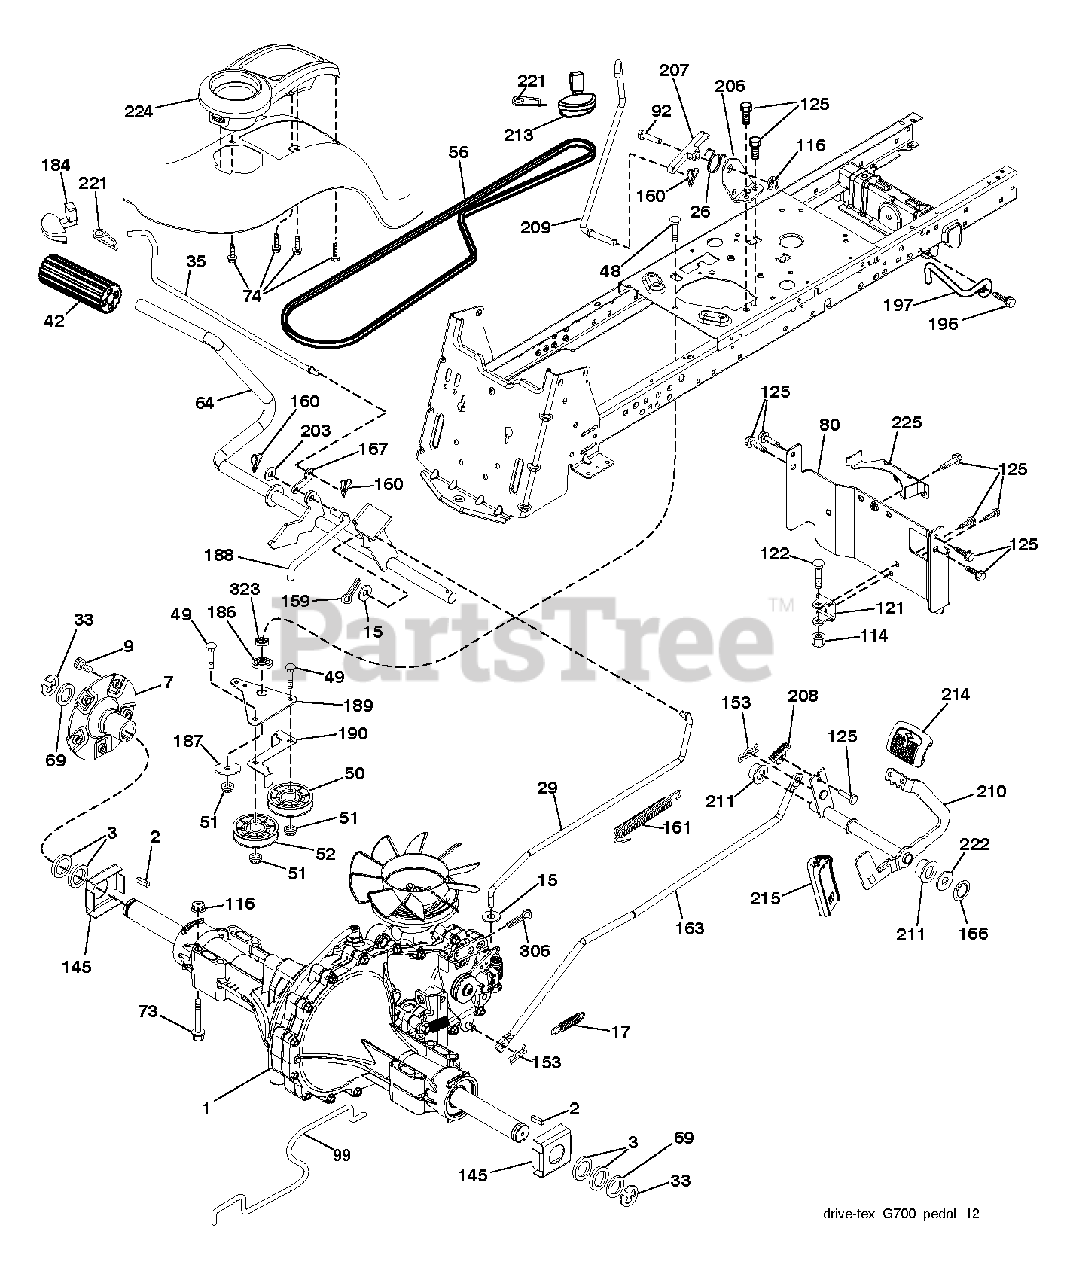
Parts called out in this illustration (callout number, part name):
2	KEY 1/4 X 2.5
3	WASHER T
7	HUB.ASM.WHEEL.REAR.23"TEX
9	HUB BOLT
15	WASHER
17	SPRING.BRAKE.HG3000/3500
26	SPRING.RETURN.CRUISE
29	ROD BRAKE
33	E RING HYT
35	ROD.BRAKE.PARKING.STEALTH
48	BOLT.3/8-16X1.50
50	IDLER.FLAT.910.OFFSET
51	NUT LOCK FLG 3/8-16 UNC
52	IDLER.V-GROOVE.910.OFFSET
56	DRIVE BELT, LTH & YTH TRACTORS
64	SHAFT.ASM.PEDAL.BRK.CNTR
74	SCREW.HI-LO.CONSOLE
80	STRAP.TORQUE.YT.G700
92	BOLT
99	SPRING.BYPASS.YT.G700
114	NUT.71038.31-18.HEX.NYLOCK
116	NUT LOCK HEX FLANGE 5/16-18
121	BRACKET STRAP TORQUE
122	BOLT.5/16-18X2.5
125	SCREW
159	COTTER PIN
160	RETAINER CLIP
161	SPRING, RETURN LT
163	ROD PEDAL CONTROL
166	NUT.PUSH.625
167	LATCH.BRAKE.SPRING
184	HANDLE.PRKG.BRAKE.STLTH.TX.RED
186	SPACER.RETAINER
187	WASHER 12/32X2X10GA
188	LINK.CLUTCH.GROUND.DRIVE
189	BELLCRANK.GROUND.DRIVE.TRAPPED
190	KEEPER BELLCRANK ROUND DRIVE
196	SCREW 3/8-16X1
197	BRKT.ANIT-ROTATION.CLUTCH
203	WASHER
206	BRKT.MOUNT.LATCH.CRUIS
206	BRACKET.MOUNT.CRUISE.LATCH
207	LATCH.CONTROL.CRUISE
208	GEAR.SECTOR.CONTROL.CR
209	ROD.CONTROL.CRUISE.STEALTH.TEX
210	ROCKER.ASM.PEDAL.CONTR
211	BEARING.NYLON
213	KNOB.CONTROL.CRUISE
214	PEDAL.FORWARD.PAD.TEX
215	PEDAL.REVERSE.TEX.GT.4
221	RETAINER.SPRING.CLIP.H
222	WASHER 21/32 X 1-1/4 X 10 GA.
224	CONSOLE.TOOLBOX.PCH.ERGO.BLACK
306	PIN COTTER
